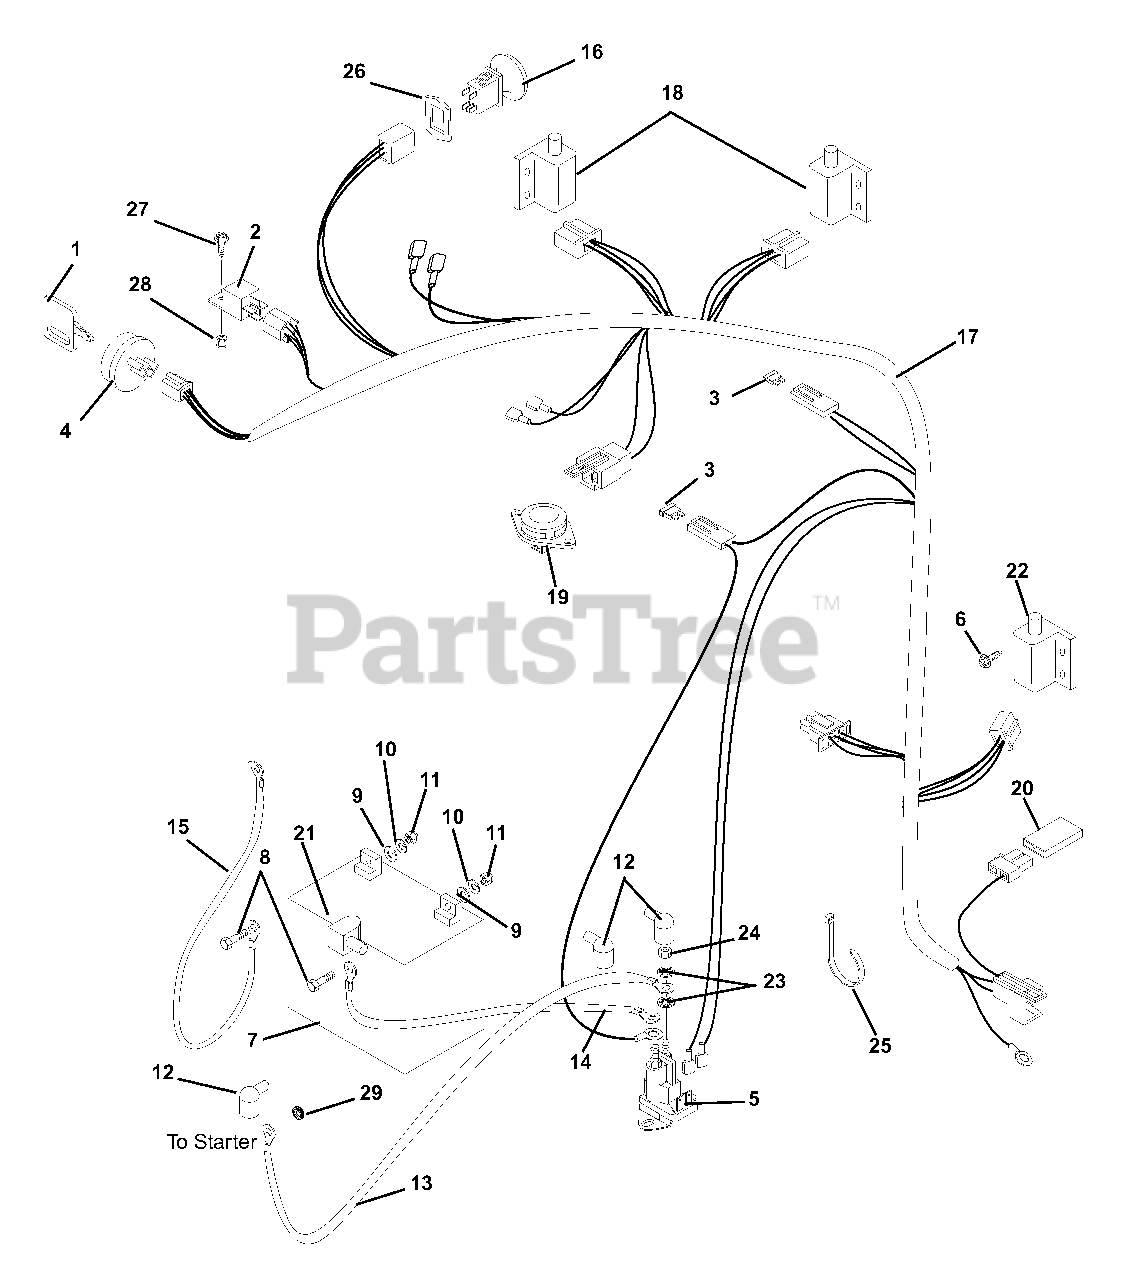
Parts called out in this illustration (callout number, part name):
1	KEY -W/CAP
2	RELAY
3	FUSE-25 AMP ATC TYPE
4	KEY SWITCH
5	SOLENOID
6	@SCR-TAP 10-24X.50 HWH TR YWZC
7	BATTERY, 300 CCA 10U1L
7	BATTERY W/ TUBE
8	@BLT-HEX .25-20X.75 GR5 YWZC
9	@WSHR-FL-STL.281X.62X.065 YWZC
10	@WSHR-LK .25X.062 REG YWZC
11	@NUT-HEX .25-20 YWZC
12	BOOT, EYELET TERMINAL
13	START CABLE 22"
14	STARTER CABLE 13"
15	GROUND CABLE .31X22.00X.31
16	SWITCH, CLUTCH
17	HARNESS, ZOOM/ZT
18	SWITCH- DOUBLE POLE N.O./N.O.
19	SWITCH- SNAP MTG N.O.
20	DIODE, CONNECTOR SHELL
21	INSULATOR
22	SWITCH,INTERLOCK
23	WSHR-LOCK INT .31 YWZC
24	NUT-JAM .31-24 YWZC
25	CABLE TIE LG 5-1/2
26	SHIM,PTO SW (DELTA #972301)
27	@SCR-MCH 10-24X.50 HWH YWZC
28	@NUT-LK-NYL 10-24 W/INSRT YWZC
29	GROMMET 1.0ID X 1.38 OD
